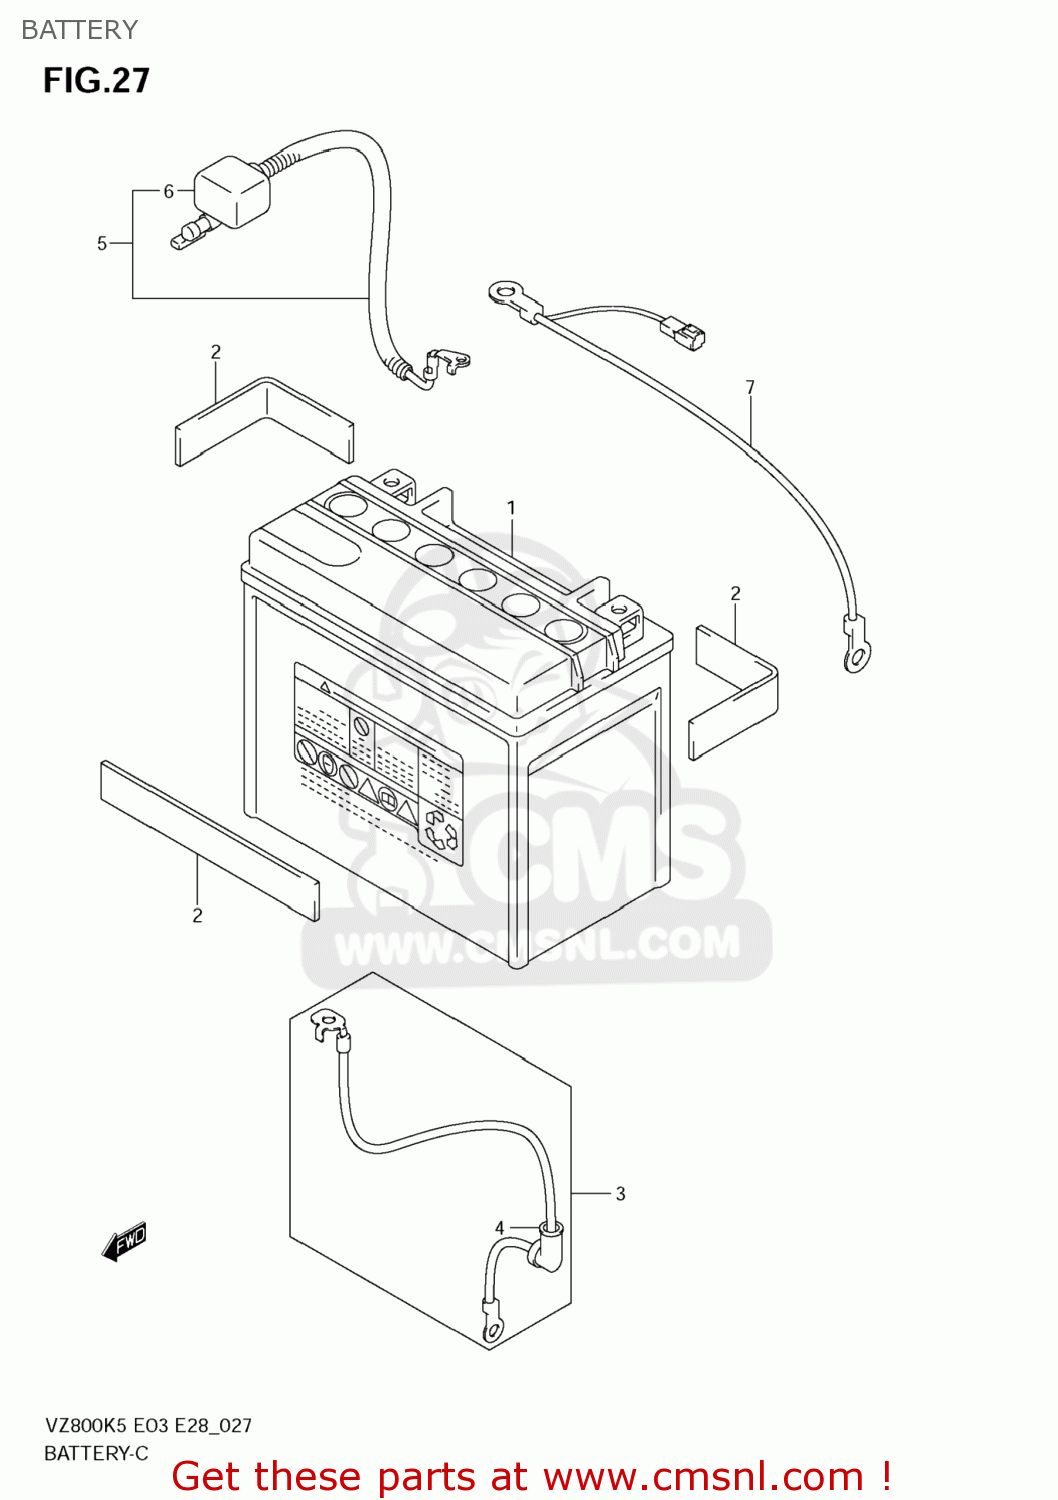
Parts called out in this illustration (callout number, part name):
1	BATTERY ASSEMBLY (12V) FTX
2	PROTECTOR(170X95X3.0)
3	WIRE,STARTER MOTOR LEAD
4	CAP,STARTER MOTOR LEAD
5	WIRE,BATTERY PLUS LEAD
6	CAP,BATTERY PLUS
7	WIRE,BATTERY MINUS
